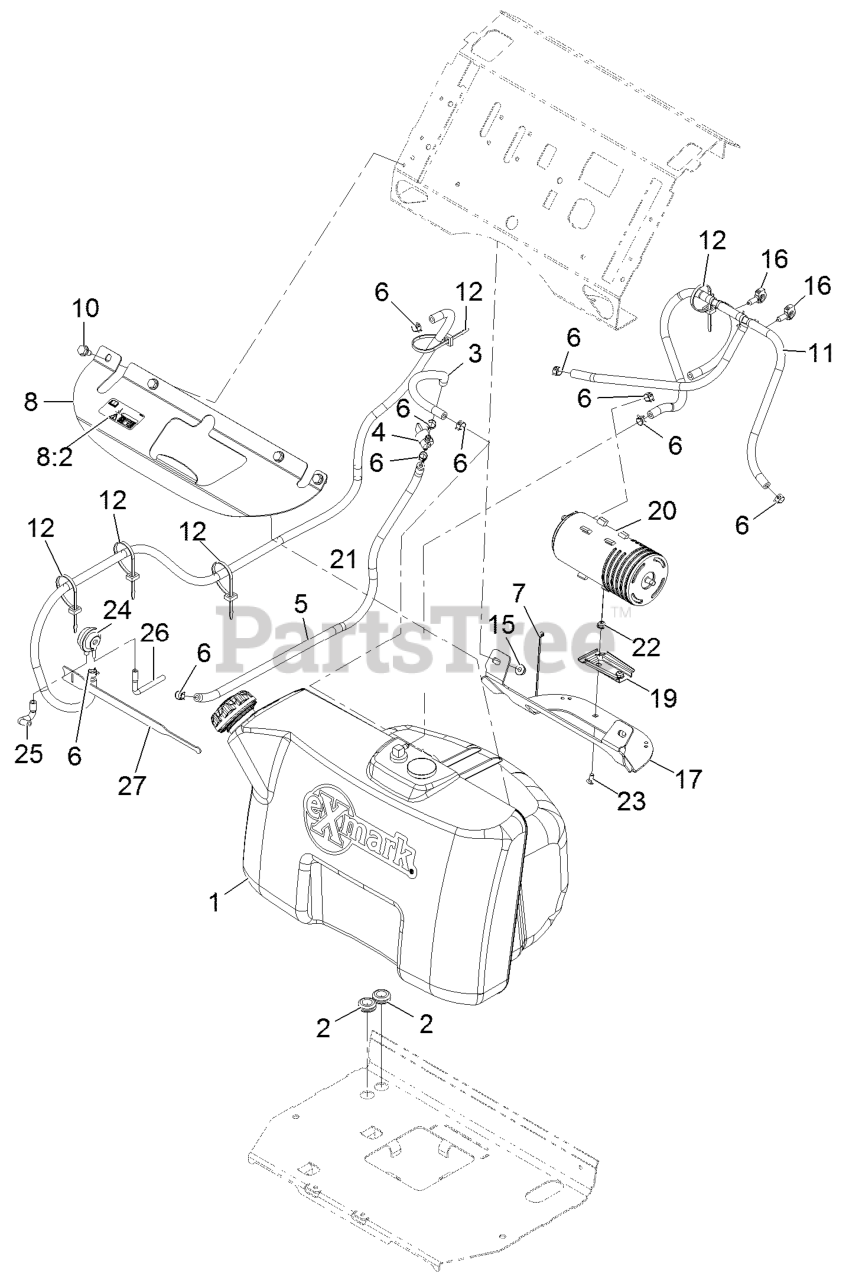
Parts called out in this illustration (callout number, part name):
2	GROMMET
3	HOSE-FUEL
4	VALVE-FUEL
5	HOSE-FUEL
6	CLAMP-HOSE
7	TIE-CABLE
8	BRACKET-TANK
8:2	Decal-Fuel Fill
10	Screw-HWH 5/16-18 X 3/4 Tf
11	VENT ASM
12	TIE-CABLE
15	NUT-HF, NI
16	CLIP-HARNESS
17	BRACKET,CARB CANISTER
19	BRACKET-CANISTER, CARBON
20	CANISTER-CARBON, 800CC
21	HOSE-FUEL .25 X 60.00, J3
23	SCREW-CARR
24	VALVE-CONTROL, VACUUM
25	HOSE-VENT, FORMED
26	HOSE-VENT, FORMED
27	STRAP-VELCRO, CABLE TIE
